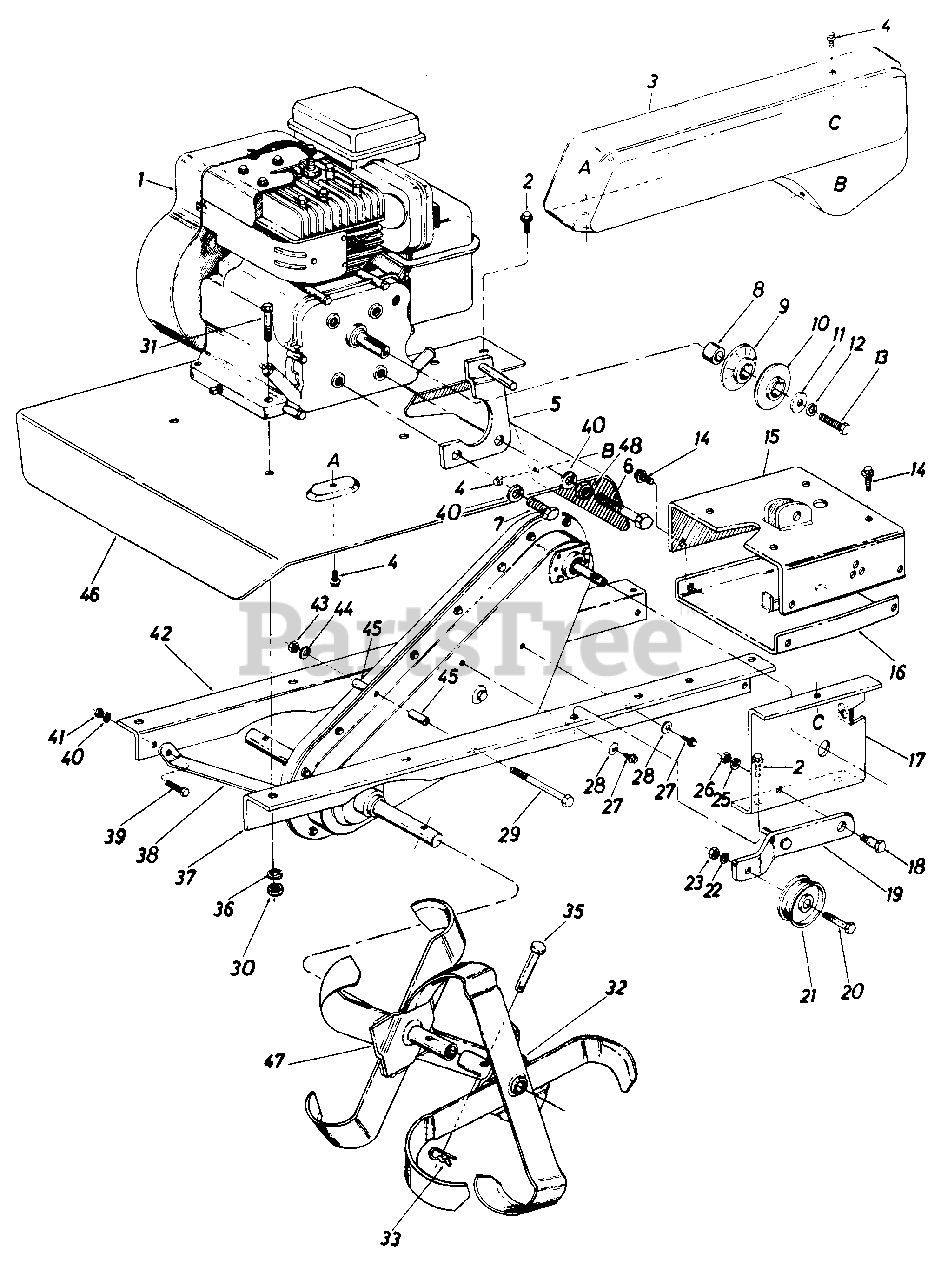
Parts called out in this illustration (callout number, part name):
1	Engine
2	Hex Wash. Hd. Self-Tap Scr. 5/16-24 x .50" Lg.
3	480 Belt Cover
4	Hex Wash. Hd. Self-Tap Scr. 1/4-20 x .50" Lg.
5	Belt Keeper Brkt. Ass'y.
6	Hex Bolt 5/16-24 x 2.25 Lg. (Grade 5)
7	Hex Bolt 5/16-24 x .62" Lg. (Grade 5)
8	Spacer
9	Pulley Half
10	Pulley Half
11	Fl-Wash. 3/8" I.D. x 1.25n O.D. x .100
12	L-Wash. 3/8" I.D.
13	Hex Scr. 3/8-24 x 1.00" Lg.
14	Hex Wash. Hd. Self-Tap Scr. 3/8-16 x .75" Lg.
15	Handle Mounting Brkt. Ass'y.
16	U-Channel Brkt. Ass'y.
17	Idler Mounting Brkt.
18	Shld. Bolt
19	Idler Brkt. Ass'y.
20	Hex Scr. 3/8-16 x 1.50" Lg.
21	Idler Pulley
22	L-Wash. 3/8" I.D.
23	Hex Nut 3/8-16 Thd.
25	L-Wash. 3/8" I.D.
26	Hex Nut 3/8-16 Thd.
27	Hex Wash. Hd. Self-Tap Scr. 1/4-20 x .50" Lg.
28	Belleville Washer. .26 I.D. x .75 O.D. x .060
29	Hex Scr. 5/16-18 x 3.0" Lg.
30	Hex Nut 5/16-18 Thd.
31	Hex Bolt 5/16-18 x 1.50" Lg.
32	See Tine Chart
33	Hairpin Cotter
35	Clevis Pin
36	L-Wash. 5/16" I.D.*
37	Frame Rail L.H.
38	Front Brace Brkt.
39	Hex Scr. 5/16-18 x .75" Lg.
40	L-Wash. 5/16" I.D.
41	Hex Cent. L-Nut 5/16-18 Thd.
42	Frame Rail R.H.
43	Hex Cent. L-Nut 5/16-18 Thd.
44	L-Wash. 5/16" I.D.
45	Spacer
46	480 Tine Shield
47	See Tine Chart
